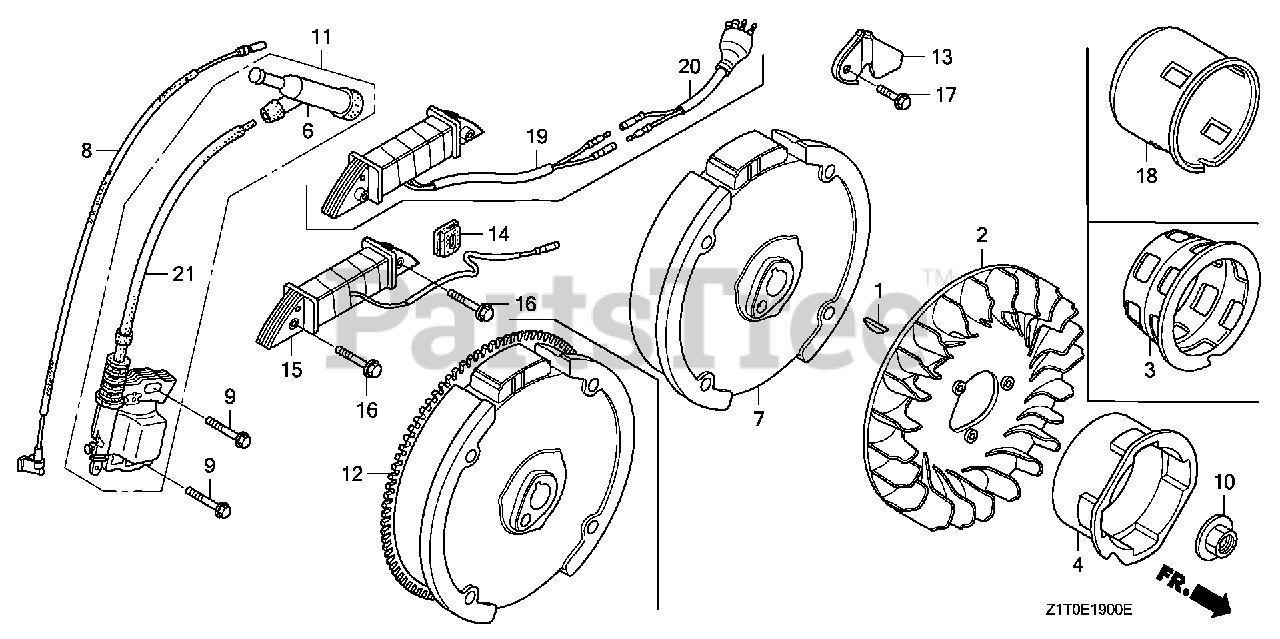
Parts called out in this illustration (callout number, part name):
1	KEY, SPECIAL WOODRUFF (25X18)
2	FAN, COOLING
4	PULLEY, STARTER
6	CAP ASSY., NOISE SUPPRESSOR
7	FLYWHEEL (KOKUSAN) (NOT AVAILABLE)
8	WIRE, STOP SWITCH (370MM)
9	BOLT, FLANGE (6X25) (CT200)
10	NUT, SPECIAL (14MM)
11	COIL ASSY., IGNITION
18	PULLEY, STARTER
